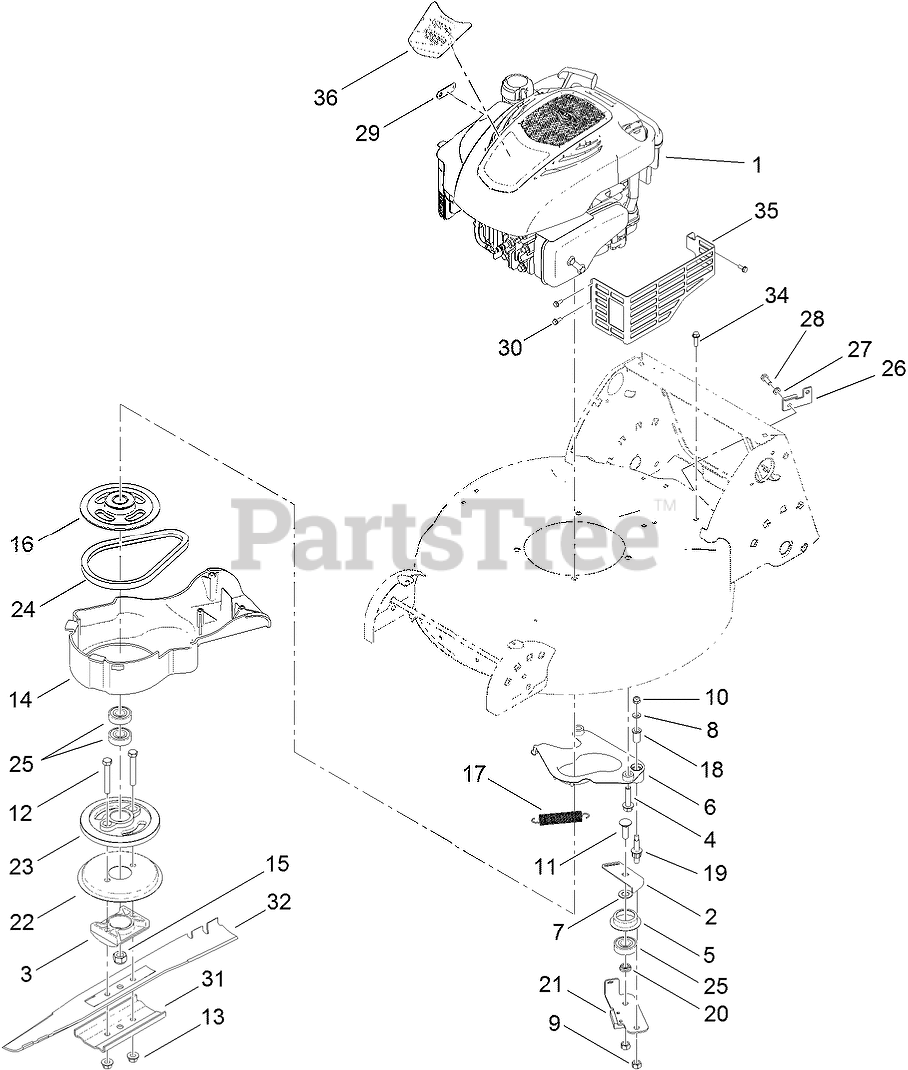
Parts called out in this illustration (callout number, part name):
2	PLATE-GUIDE
3	SUPPORT-BLADE
4	SCREW-HWH
5	RETAINER-BELT
6	PLATE-ANCHOR
7	WASHER-PLAIN
8	WASHER-FLAT
10	NUT-LOCK, NI
11	BOLT-CARR
12	SCREW-HH
13	NUT-LOCK
14	COVER-BBC
15	NUT-HEX
16	PULLEY
17	SPRING-TENSION, BRAKE
18	BUSHING
19	BOLT-SHOULDER
20	SPACER-BEARING
21	BRAKE ARM ASM
22	DISC
23	DRUM
24	BELT
25	BEARING-BALL
26	CLAMP-CABLE, BBC
27	WASHER-LOCK
28	SCREW-HH
29	PLATE-TERMINAL
30	SCREW-TAPTITE
31	SUPPORT-BLADE
32	BLADE-21 INCH
34	SCREW-HWH
35	SHIELD-MUFFLER
36	DECAL-SHROUD
